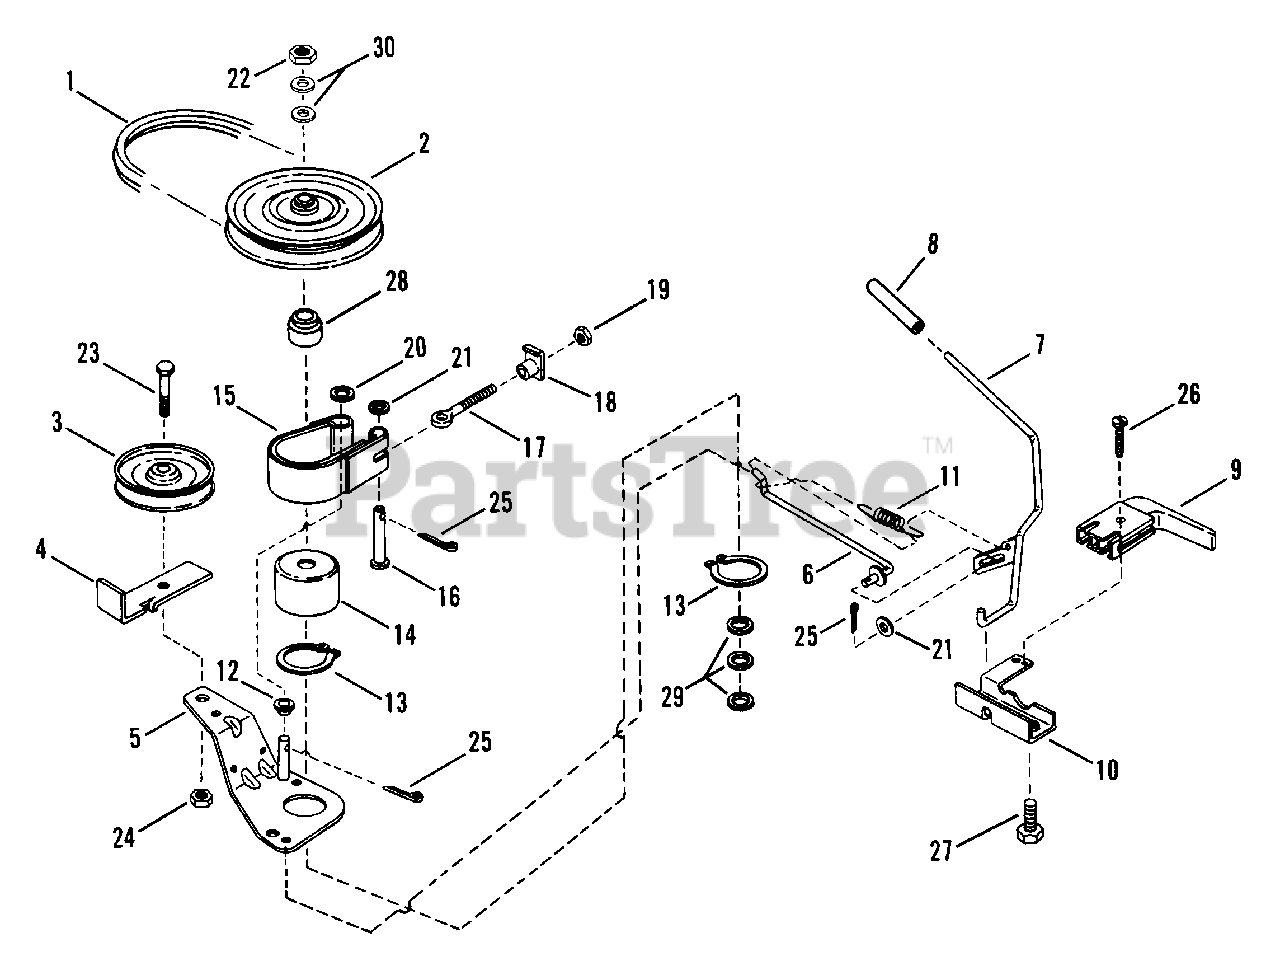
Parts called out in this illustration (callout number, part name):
1	BELT, Drive
2	PULLEY, Spindle
3	PULLEY, Idler
4	RESTRICTOR, Belt
5	ARM, Idler
6	ROD, Idler
7	HANDLE, Blade Lever (On-Off)
8	GRIP, Handle
9	SWITCH, Deck Interlock
10	MOUNT, Handle
11	SPRING, Blade Handle
12	SPACER
13	RING, 2" External Retaining
14	DRUM, Brake
15	BAND, Brake Assembly
16	PIN, 1/4 x 1-5/8" Clevis
17	BOLT, 1/4-20 Eye
18	NUT, 1/4-20 Tee
19	NUT, 1/4-20 Hex
20	WASHER, 3/8" Flat
21	WASHER, 1/4 Flat
22	NUT, 3/4-16 Hex Jam
23	SCREW, 3/8-24 x 1 3/4" Hex Cap
24	NUT, 3/8-24 Hex Lock
25	PIN, 3/32 x 3/4" Cotter
26	SCREW, #10-32 x 1" Self-Tap
27	SCREW, 1/4-20 x 5/8" Self-Tap
28	HUB, Pulley
29	WASHER, 49/64 x 1-1/8" Flat
30	WASHER, 49/64 x 1-1/2" Flat
